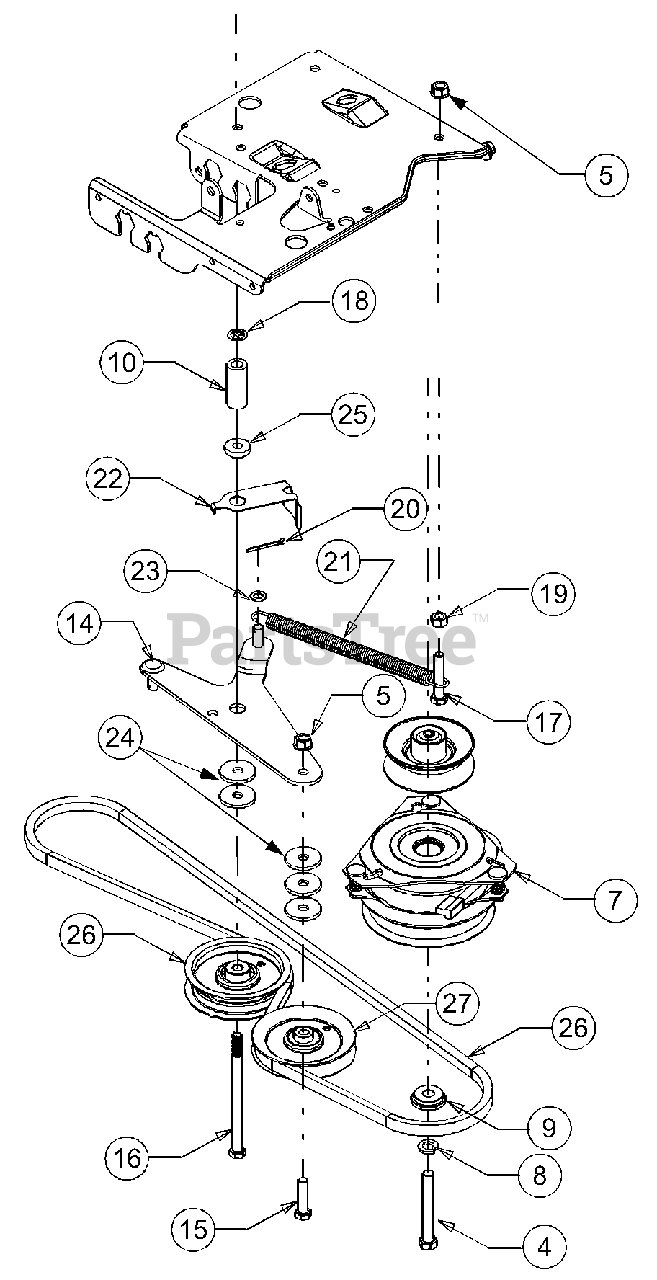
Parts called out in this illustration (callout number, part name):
4	Screw, Hex Cap, 7/16-20 x 3.25 GR5
5	Nut, Nylon Lock, 3/8-16
7	Clutch, Electric PTO (Model 1018)
8	Washer, Lock, 7/16, Regular Duty
9	Spacer, Shoulder, 1.38 x .445 x .36
10	Spacer, 3/8 x 1.54
16	Screw, 3/8-16, 5.5
17	Screw, 3/8-16, 2.0
18	Push Nut, 3/8
19	Nut, 3/8-16
20	Cotter Pin, 1/8 x 1.25
21	Spring, Extension .62 x 6.12
22	Belt Guard
23	Washer, Flat .385 x .62 x .063
24	Washer, Flat .406 x 1.5 x .11 Ga
25	Shoulder Spacer, .380
26	Pulley, Idler, 3.5
27	Pulley, Idler, 4.0
